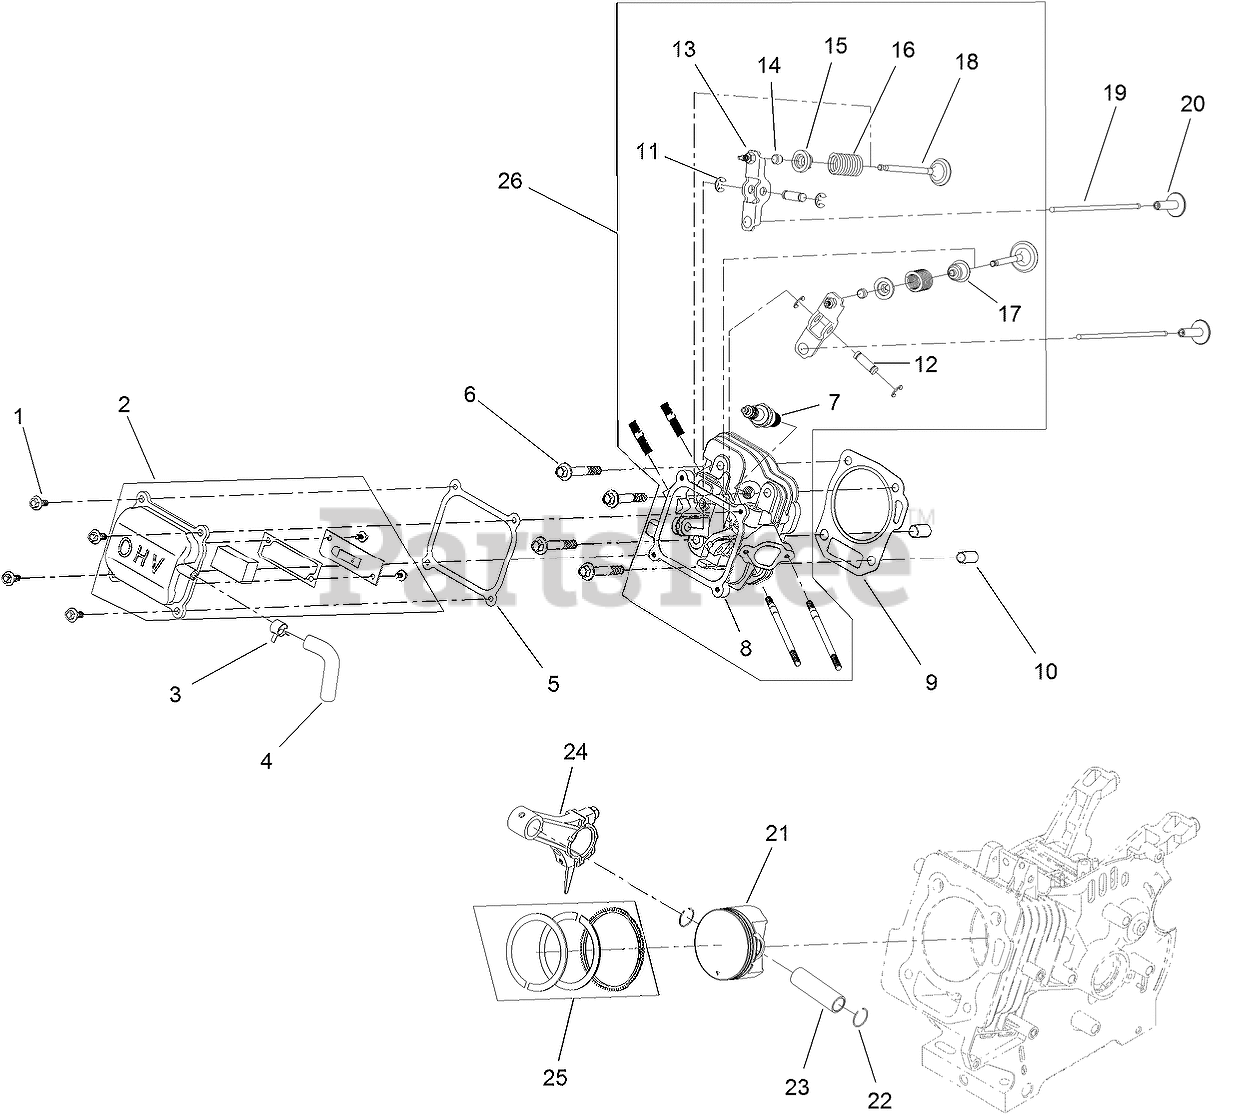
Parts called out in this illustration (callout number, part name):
1	SCREW-HHF
2	VALVE COVER ASM
3	CLAMP-HOSE
4	TUBE-BREATHER
5	GASKET-COVER, VALVE
6	SCREW-FLANGE
7	SPARK PLUG
8	HEAD-CYLINDER
9	GASKET-HEAD
10	PIN-DOWEL
11	E-CLIP
12	PIN-ARM, ROCKER
13	ROCKER ARM ASM
14	ROTATOR-VALVE
15	RETAINER-SPRING, VALVE
16	SPRING-VALVE
17	SEAL-STEM, VALVE
18	SET-VALVE
19	ROD-PUSH
20	TAPPET-VALVE
21	PISTON
22	CLIP-PIN, PISTON
23	PIN-PISTON
24	CONNECTING ROD ASM
25	SET-RING, PISTON
26	COMPLETE HEAD ASM
